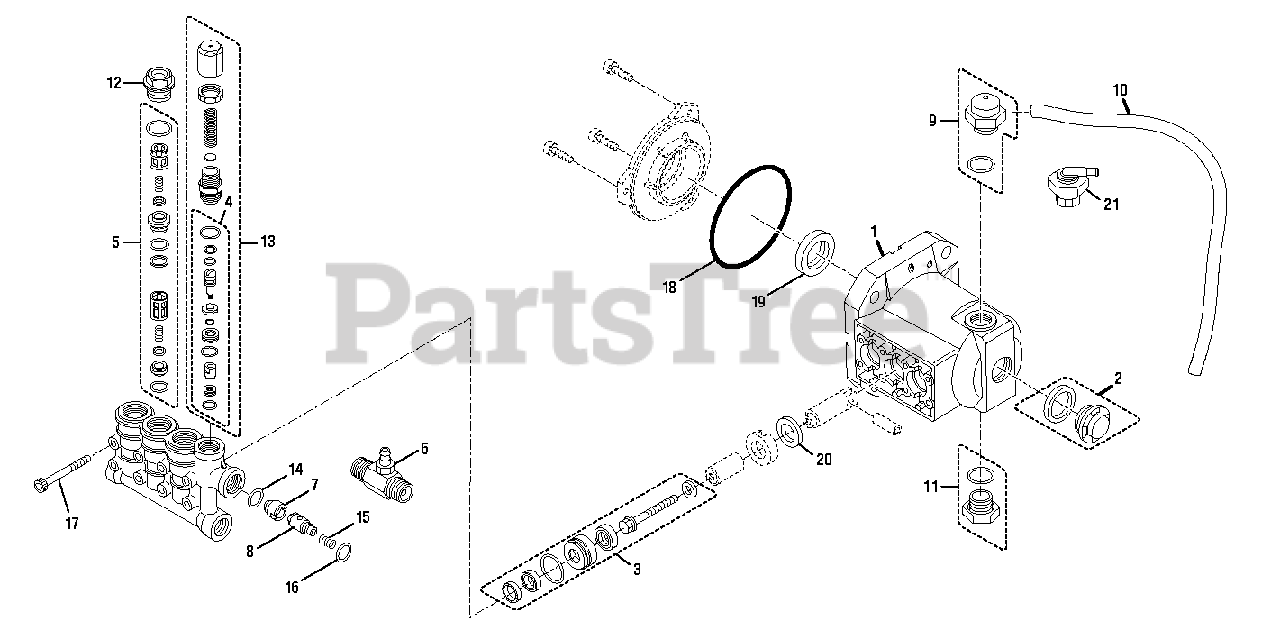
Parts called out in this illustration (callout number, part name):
1	Pump Assembly
2	Bubble Oil Gauge w/Gasket
4	O-Ring Kit
5	Valve Kit
6	Chemical Injector
7	Check Valve Seat
8	Check Valve w/O-Ring
9	Vent Cap (CAT)
10	Tube (Optional, 11 in)
11	Drain Plug
12	Plug
13	Unloader Assembly
21	Vent Cap (Optional)
